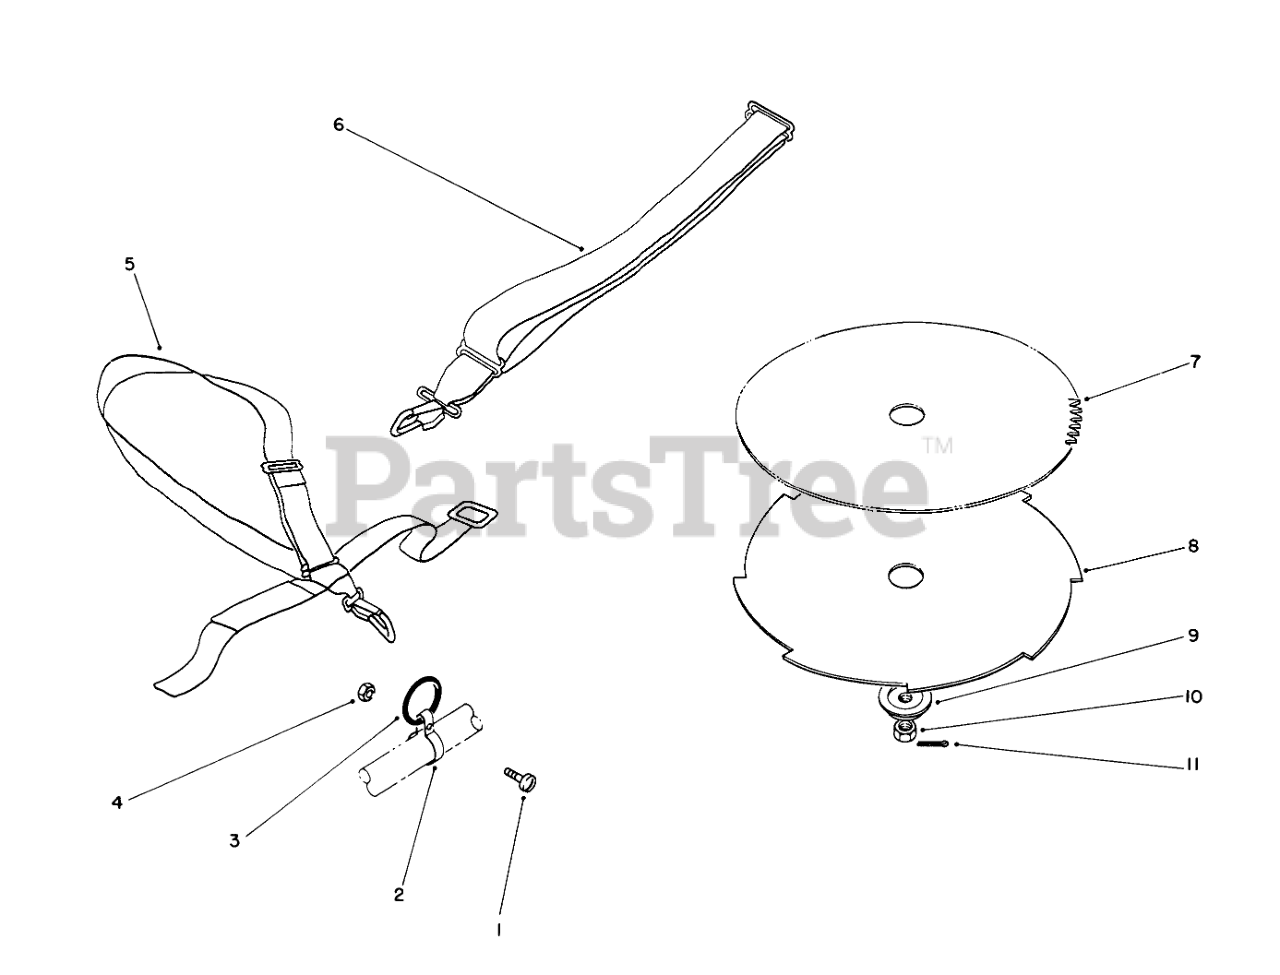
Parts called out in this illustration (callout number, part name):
1	SCREW-SRH
2	HARNESS CLAMP
3	RING-HARNESS
4	NUT-LOCK, NI
5	Deluxe Harness
6	Harness
7	SAW BLD PKG(8", 80T)
8	BRUSH BLD PKG(8",8T)
9	BLADE ADAPTER KIT
11	1/16 X 1 LG COTTER PIN
